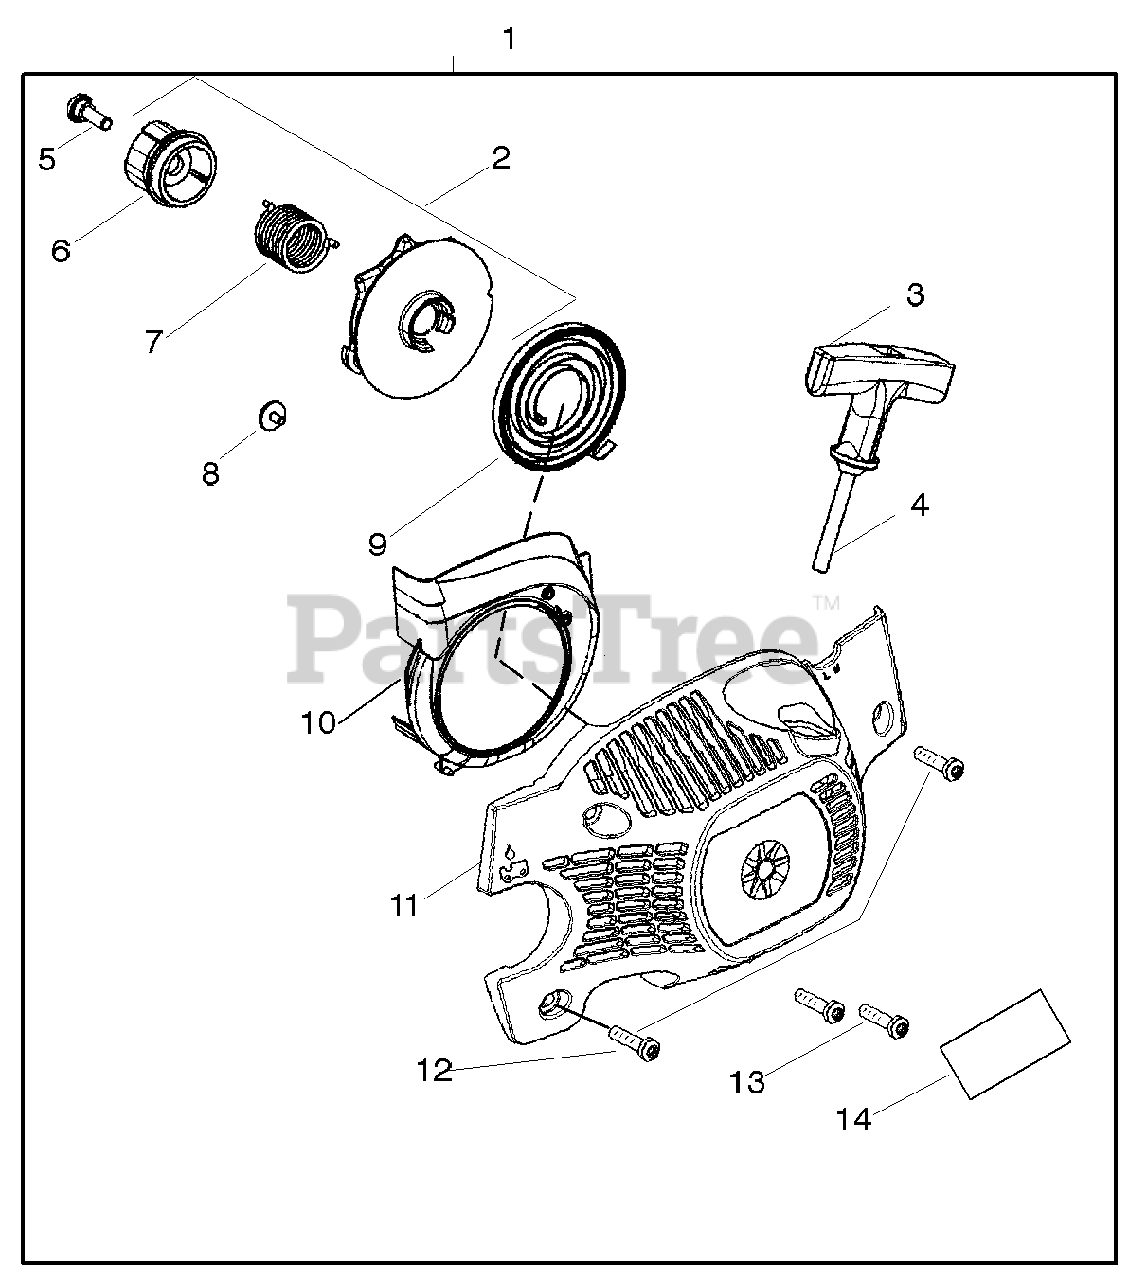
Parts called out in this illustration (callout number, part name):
1	Kit-Fan Hsg / Starter
2	Kit-Starter EPS
3	Handle-Starter
5	Screw-shoulder
7	Spring-EPS
9	Spring-Starter
10	Baffle-Air
11	Assy-Fan Hsg. w/eyelet
14	Decal - Fan Housing
